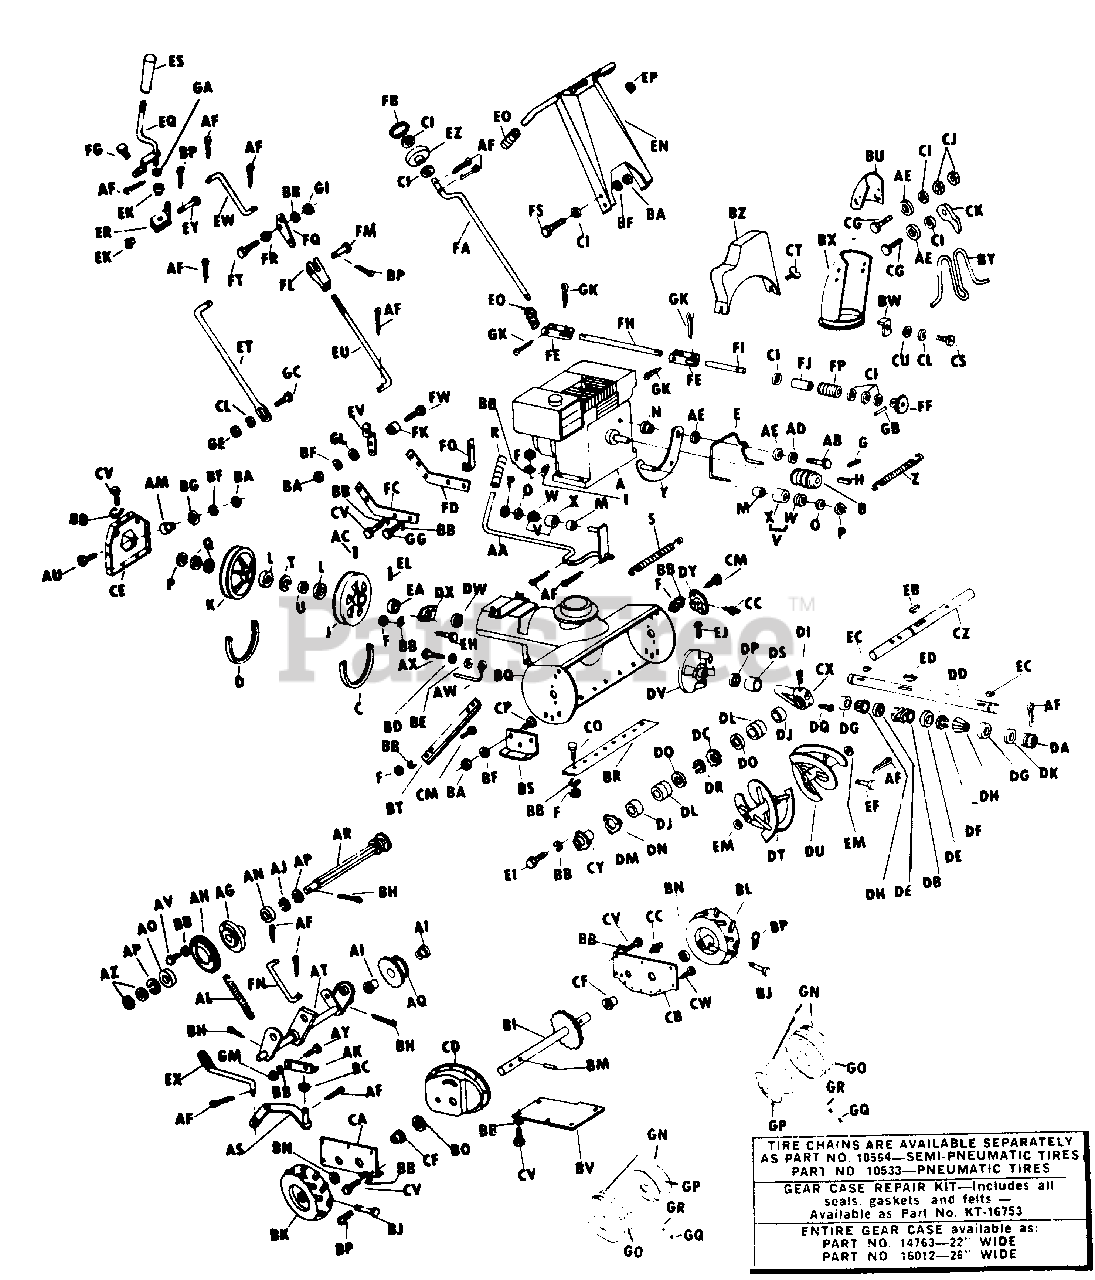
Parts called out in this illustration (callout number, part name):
A	Engine-5 H.P. B&S Model 130202, Type 0196-02
B	Engine Pulley-6, 7, 8 H.P.
C	V-Belt Auger Drive-5 H.P.
D	V-Belt, Traction Drive, 5 H.P.
E	Belt Finger-5 H.P.
F	5/16-18 Hex Nut-Pl.
G	5/16-18 x 5/16 Setscrew
H	1/4 x 1/4 x 1 3/4 Key-6, 7, 8 H.P.
I	5/16 Flatwasher-Pl.
J	Pulley-Impeller Drive
K	Pulley-Traction Drive
L	Bearing
M	Bushing
N	Pivot Bushing
O	Washer
P	Snap Ring
Q	Washer
R	Grip
S	Spring
T	Snap Ring
V	Idler and Bearing Assembly
W	Idler
X	Bearing
Y	Idler Arm Assembly
Z	Spring
AA	Idler Arm Assembly
AB	1/2-20 x 1/2 Hex Hd. Capscrew-Pl.
AC	3/8-16 Socket Setscrew
AD	1/2 Spring Lockwasher
AE	1/2 SAE Flatwasher-Pl.
AF	1/8 x 3/4 Cotter Pin-Pl.
AG	Friction Wheel Hub
AH	Friction Wheel Roller
AI	Bushing
AJ	Snap Ring
AK	Shifter Slide
AL	Spring
AM	Pivot Bushing
AN	Bearing
AO	Bearing
AP	Snap Ring
AQ	Countershaft Gear Assembly-w/Bushings
AR	Traction Drive Shaft Assembly
AS	Bellcrank Assembly
AT	Traction Drive Support Arm Assembly
AU	3/8-16 x 1 3/4 Hex Hd. Capscrew-Pl.
AV	5/16-18 x 1/2 Hex Hd. Capscrew-Pl.
AW	Belt Finger
AX	1/4-20 x 1/2 Hex Capscrew-Pl.
AY	5/16-18 x 1 1/4 Wafer Hd. Bolt
AZ	Washer
BA	3/8 Hex Nut-Pl.
BB	5/16 Spring Lockwasher-Pl.
BC	5/16 SAE Flatwasher
BD	1/4 Spring Lockwasher-Pl.
BE	1/4 Flatwasher
BF	3/8 Spring Lockwasher-Pl.
BG	Washer
BH	1/8 x 1 Cotter Pin-Pl.
BI	Axle Assembly
BJ	Clevis Pin
BK	Tire & Wheel Ass'y.-R.H.-Semi-pneumatic
BL	Tire & Wheel Ass'y.-L.H.-Semi-pneumatic
BM	1/8 x 1-1/4 Roll Pin
BN	Washer
BO	Washer
BP	Spring Clip
BQ	Main Frame Assembly-5 H.P., 22"
BR	Scraper Blade-22"
BS	Skid
BT	Drift Cutter
BU	Deflector
BV	Inspection Cover
BW	Chute Clip
BX	Chute & Ring Assembly
BY	Chute Guard
BZ	Belt Guard Assembly
CA	Frame Assy.-Lower Half-R.H.
CB	Frame Ass'y.-Lower Half-L.H.
CC	Grease Fitting
CD	Gear Case Cover
CE	Backing Plate Ass'y.
CF	Axle Bearing
CG	3/8-16 x 1 Short Neck Carriage Bolt-Pl.
CI	3/8 Flatwasher-Pl.
CJ	3/8-16 Hex Jam Nut-Pl.
CK	Wing Nut
CL	1/4 Spring Lockwasher
CM	5/16-18 x 3/4 Hex Hd. Capscrew Pl.
CO	5/16-18 x 3/4 Wafer Hd. Bolt
CP	3/8 Carriage Bolt-Pl.
CT	1/4-20 x 1/2 Shoulder Thumb Screw
CU	1/4 Flatwasher-Pl.
CV	5/16-18 x 3/4 Hex Capscrew-Pl.
CW	#10 x 1/2 Hex Hd. Sheet Metal Screw
CX	Gear Case
CY	Cover-Gear Case
CZ	Shaft-Output-22"
DA	Adjustment Plug
DB	Worm
DC	Worm Wheel
DD	Shaft-Auger Input
DE	Spacer-Worm
DF	Retaining Ring
DG	Bearing Cup
DH	Bearing Cone
DI	Vent Plug Ass'y.
DJ	Seal
DK	O-Ring
DL	Bearing
DM	Gasket
DO	Washer
DP	Seal
DQ	Pipe Plug
DR	Snap Ring
DS	Bearing
DT	Auger Ass'y.-R.H.-22"
DU	Auger Assty.-L.H.-22"
DV	Impeller Assembly
DW	Bearing
DX	Stamping
DY	Bearing
EA	Collar-Bearing w/Setscrews
EB	1/4 x 7/8 Woodruff Key-H.T
EC	3/16 x 5/8 Hypro Key
ED	Hypro Key
EF	Shear Pin
EH	5/16-18 x 3/4 Carriage Bolt-Pl.
EI	5/10-18 x 1 Hex Hd. Capscrew-H.T.
EJ	3/8-16 x 1/2 Sq. Hd. Cup Pt. Setscrew-Pl.
EK	Bushing
EL	1/4-20 x 1/4 Setscrew
EM	Washer
EN	Handle Bar Assembly
EO	Grip
EP	Plug Button
EQ	Control Lever Assembly
ER	Bracket Assembly-w/Bushing
ES	Control Knob
ET	Shifter Rod
EU	Control Rod
EV	Bell Crank
EX	Shifter Rod End
EY	Clevis Pin
EZ	Knob
FA	Crank
FB	Plug
FC	Handle Bracket-R.H.
FD	Handle Bracket-L.H.
FE	Universal
FF	Sprocket Assembly
FG	Pivot Pin Ass'y
FH	Chute Shaft
FI	Sprocket Shaft
FJ	Spacer
FK	Pivot Bushing
FL	Clevis
FM	Clevis Pin
FO	Chute Shaft Support
FP	Spring
FQ	Bellcrank
FR	Pivot Bushing
FS	3/8-16 x 1 Acorn Hd. Bolt-Pl.
FT	5/16-18 x 1 Hex Hd. Capscrew-Pl.
FW	3/8-16 x 2 1/4 Hex Hd. Capscrew- Pl.
GA	7/16 SAE Flatwasher-Pl.
GB	1/8 x 1 1/2 Cotter Pin
GC	1/4-20 x 3/4 Carriage Bolt-Pl.
GE	1/4-20 Hex Nut-Pl.
GG	5/16-18 x 1 Hex Capscrew-Pl.
GI	5/16-18 Hex Nut-Pl.
GK	Special Stainless Steel Cotter Pin
GL	5/16 Flatwasher-Pl.
GM	5/16-18 Hex Locknut
GN	Wheel & Tire Ass'y.-Pneumatic
GO	Tire-Pneumatic
GP	Wheel-Pneumatic
GQ	Valve Cap
GR	Valve Stem
